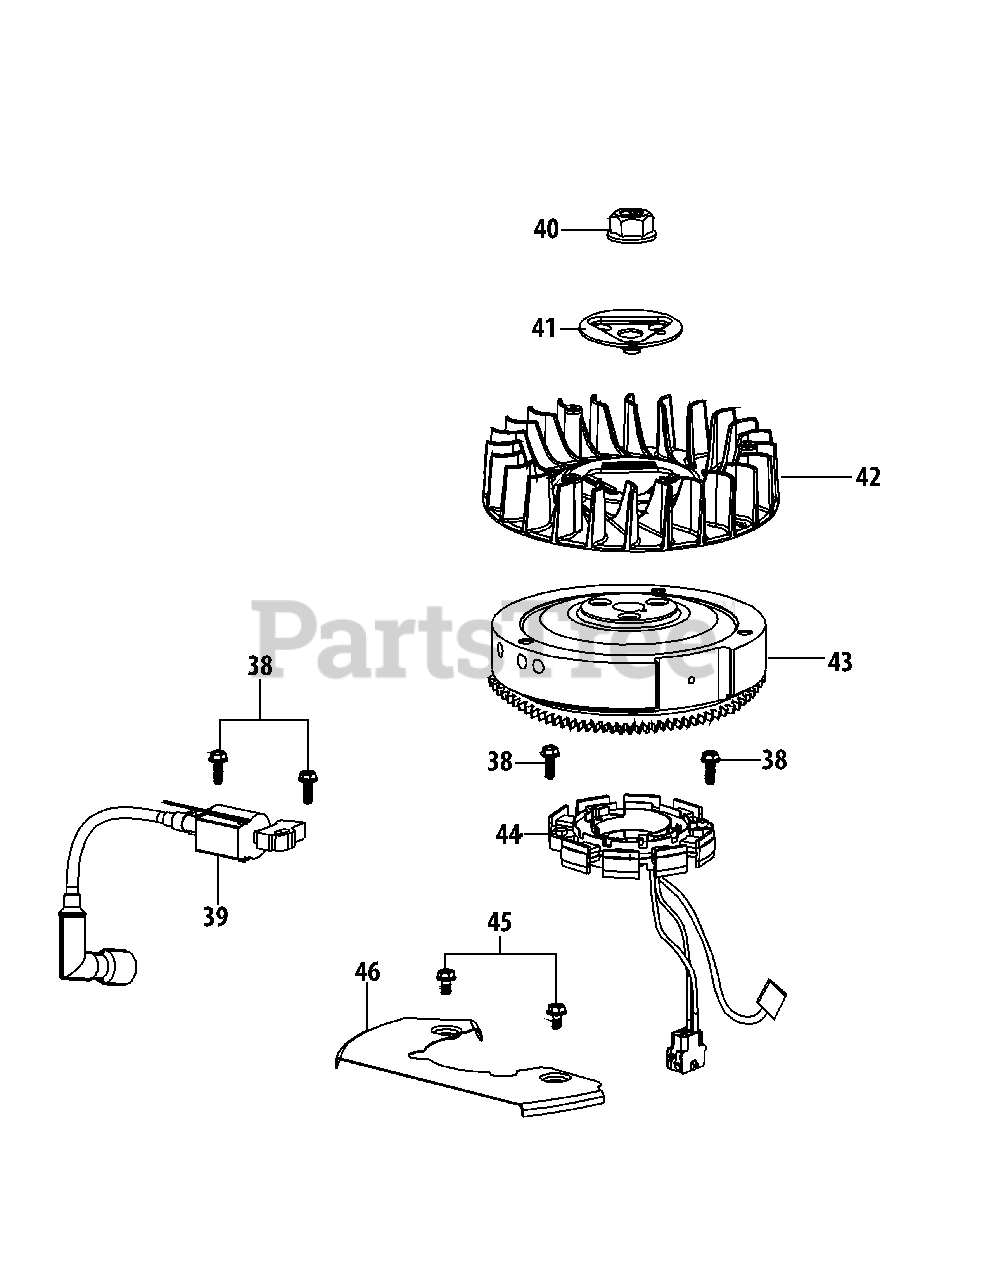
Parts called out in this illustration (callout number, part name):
38	Bolt M6×28
39	Ignition Coil Assembly
40	Flywheel Nut M16×1.5
41	Fan Mounting Plate
42	Cooling Fan
43	Flywheel
44	Coil Assy. Charge
45	Bolt M6×10
